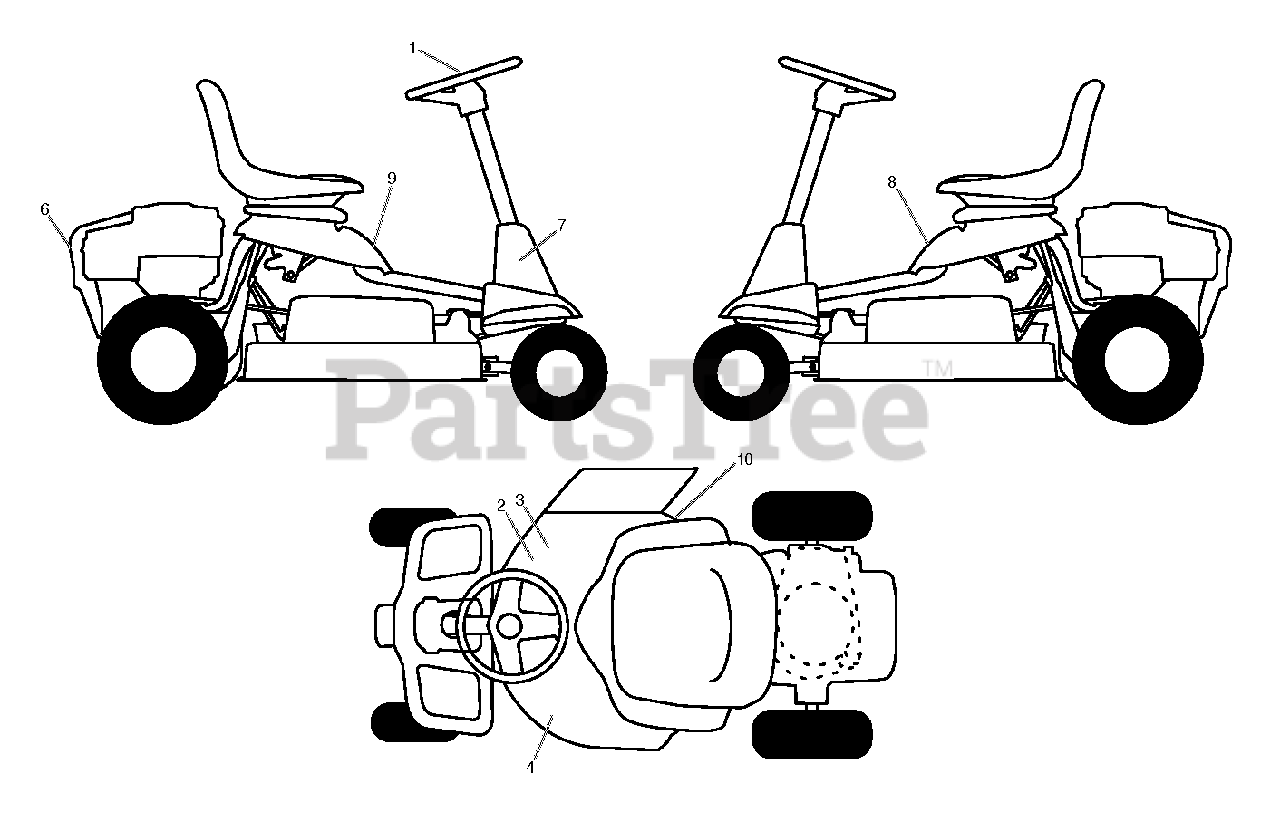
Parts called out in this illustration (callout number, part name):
2	DECAL.DECK.BELT.ROUTING.LRVB
3	DECAL.WARN.DFLECT/CTFINGR.SRD
4	DECAL.LRVB.DECK.301.PPRO
5	DECAL.ENG.B&S.11.5HP.PWR.BLT
